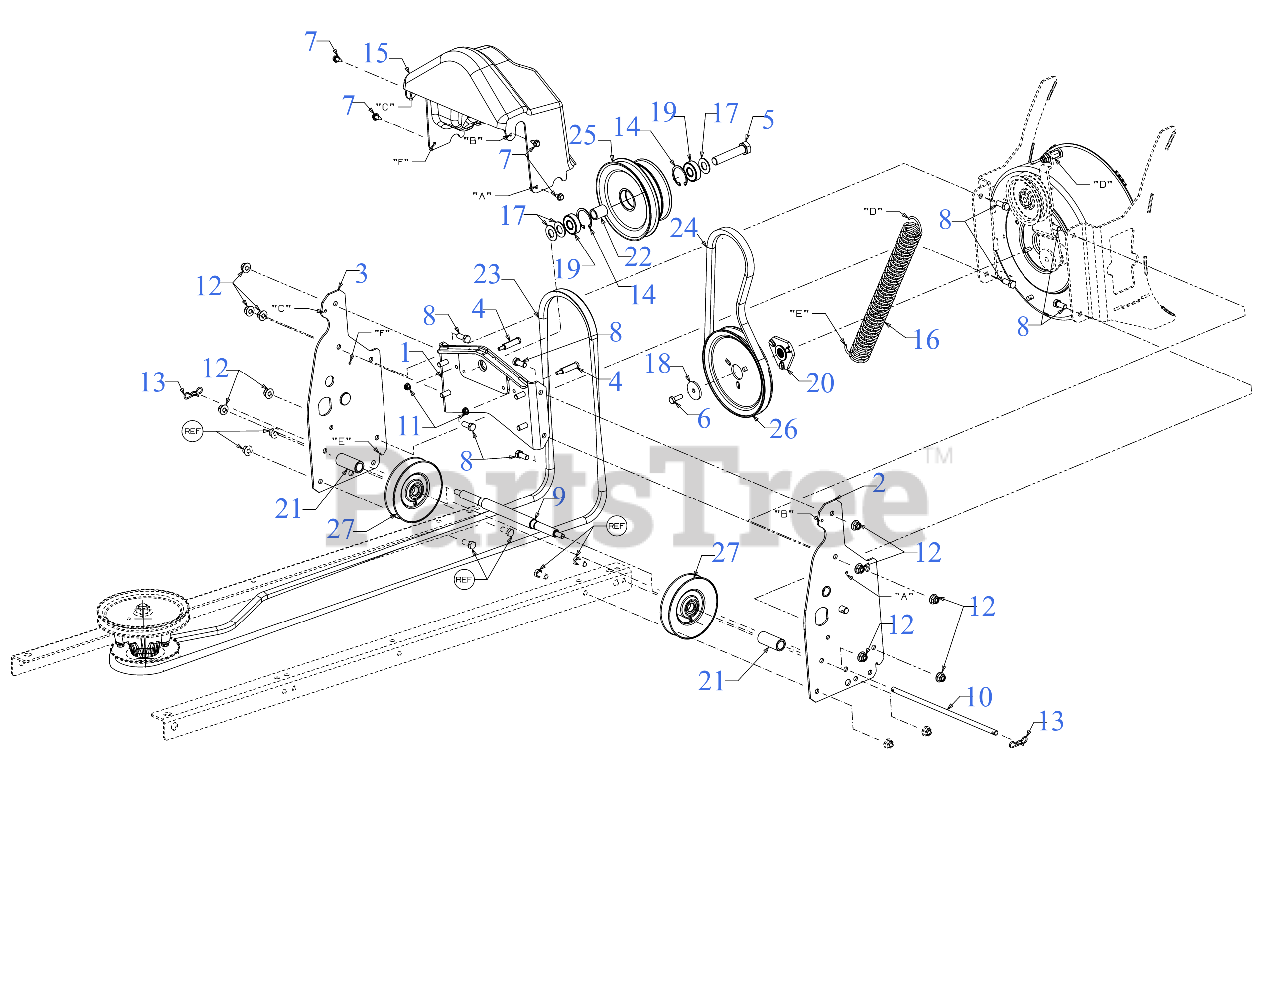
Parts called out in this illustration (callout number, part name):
1	DOUBLE PULLEY BRACKET (POWDER BLACK)
2	FRAME BRACKET (RH) (POWDER BLACK)
3	FRAME BRACKET (LH) (POWDER BLACK)
4	SHOULDER BOLT
5	SCREW 5/8-18X3.0 GR5
6	SCREW 5/16-24 x .875 GR5
7	SCREW 1/4-20X.625
8	SCREW 3/8-16 x .880 GR5
9	MULE DRIVE SHAFT
10	BELT KEEPER ROD
11	FLANGE LOCK NUT
13	BOW TIE COTTER PIN
14	INTERNAL SNAP RING
15	BELT COVER
16	EXTENSION SPRING 1.6 OD x 7.584
17	FLAT WASHER
18	FLAT WASHER
19	BALL BEARING
20	ADAPTER PULLEY .75 DIA W/PINS
21	IDLER PULLEY SPACER
22	DOUBLE PULLEY SPACER
23	V-BELT B SEC x 138.4
24	V-BELT B SEC x 39.98
25	DOUBLE V-PULLEY
26	V-PULLEY
27	V-IDLER PULLEY
